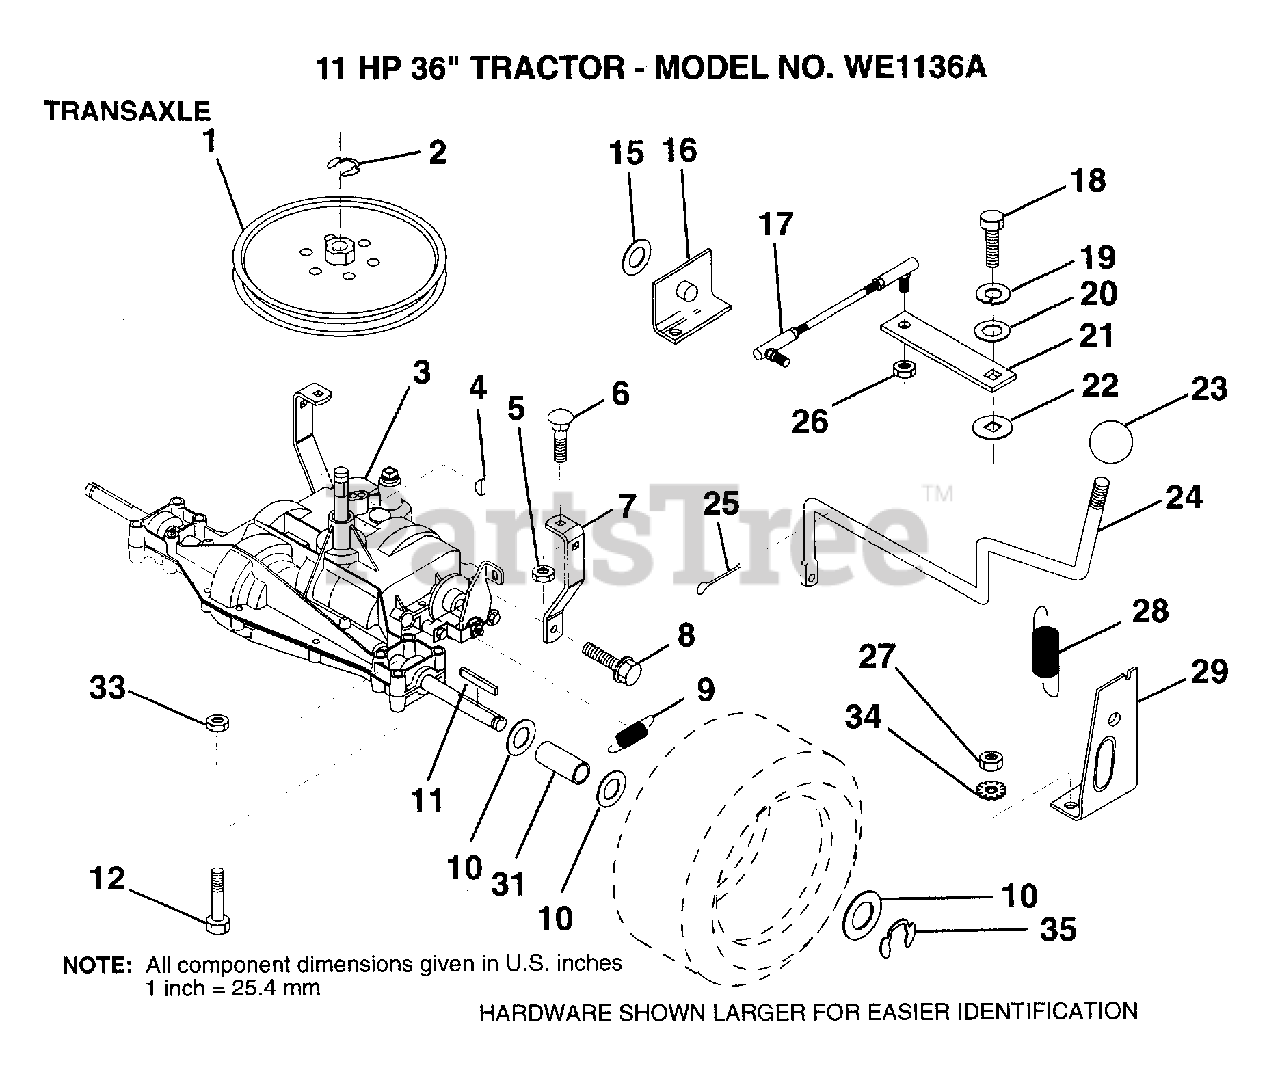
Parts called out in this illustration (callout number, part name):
1	PULLEY
6	BOLT
7	"STRAP,TORQUE"
8	SCREW
10	WASHER
11	SQUARE KEY
12	BOLT
16	"SUPT,HDLE SHT LH"
17	"LINK,SHIFT"
19	LOCKWASHER
20	WASHER LT
21	ARM SHIFT
22	WASH-SHFT PLT LT
23	KNOB T (1/2-HOLE)
24	"ROD,SHIFT"
25	PIN COTTER 1/8
26	NUT.LOCK.5/16-24
28	"SPRING,EXT"
29	"SUPT,HDLE RH"
31	SPACER
34	LOCKWASHER.5/16.E
35	E-RING LT
